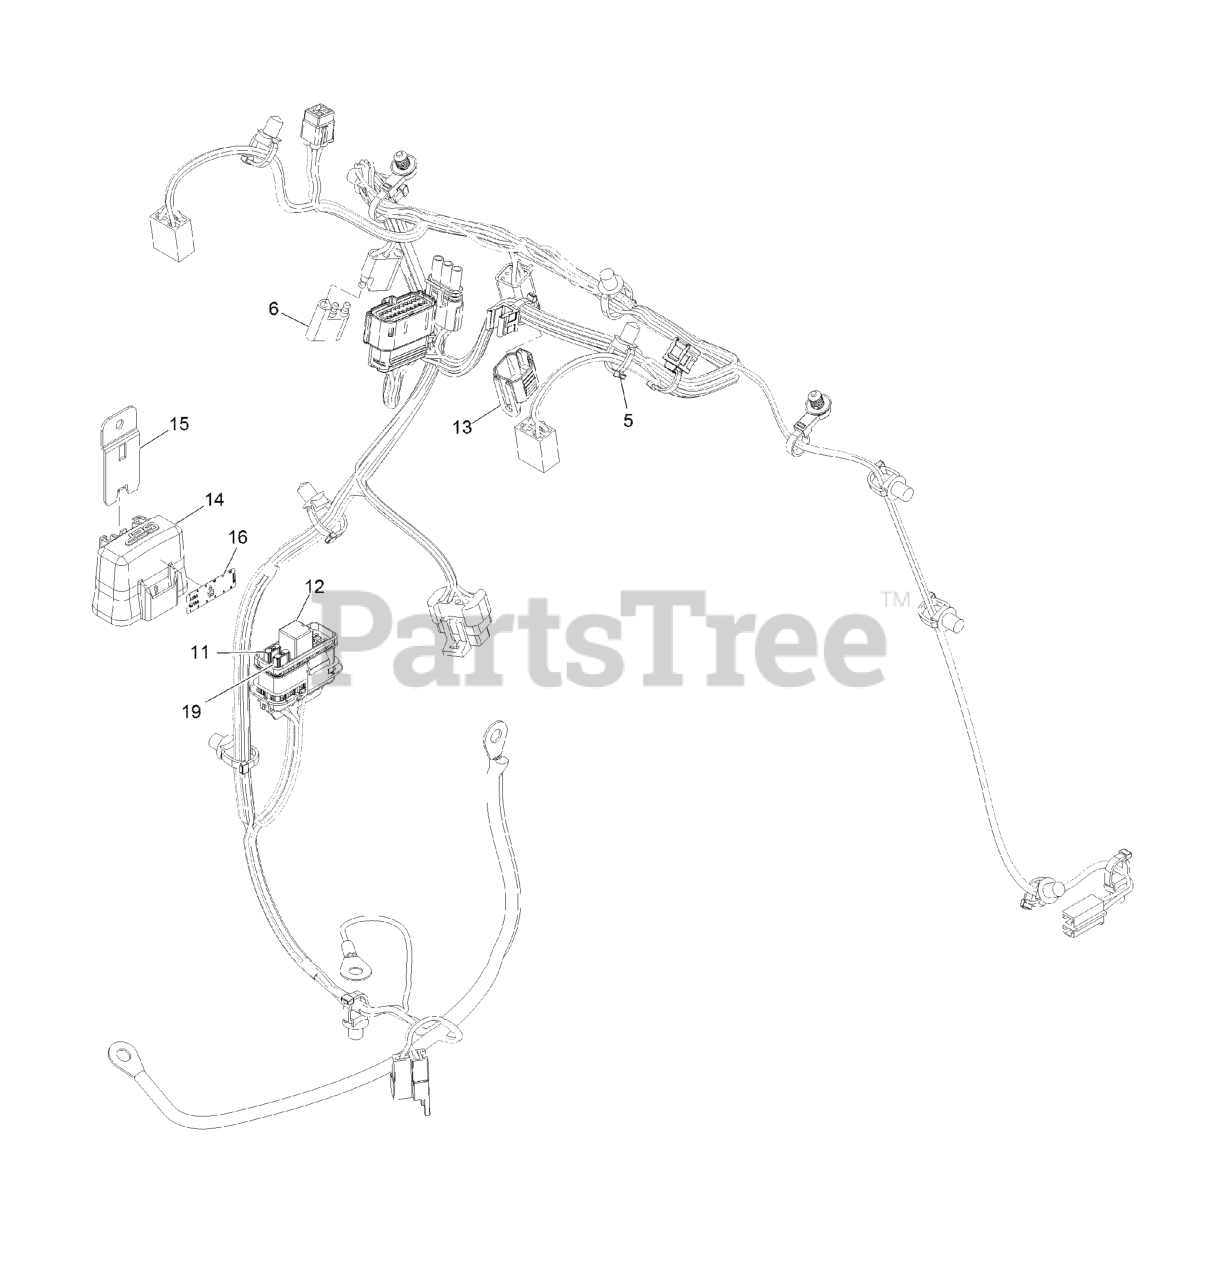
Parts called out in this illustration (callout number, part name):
5	CLIP-TIE
6	Cap-Plug
11	FUSE-MINI BLADE, 20 AMP
12	RELAY-MICRO
13	CAP-PLUG, 6 WAY
14	COVER-BLOCK, FUSE
15	CLIP-MOUNTING
16	DECAL-FUSE
19	FUSE-MINI BLADE, 15 AMP
